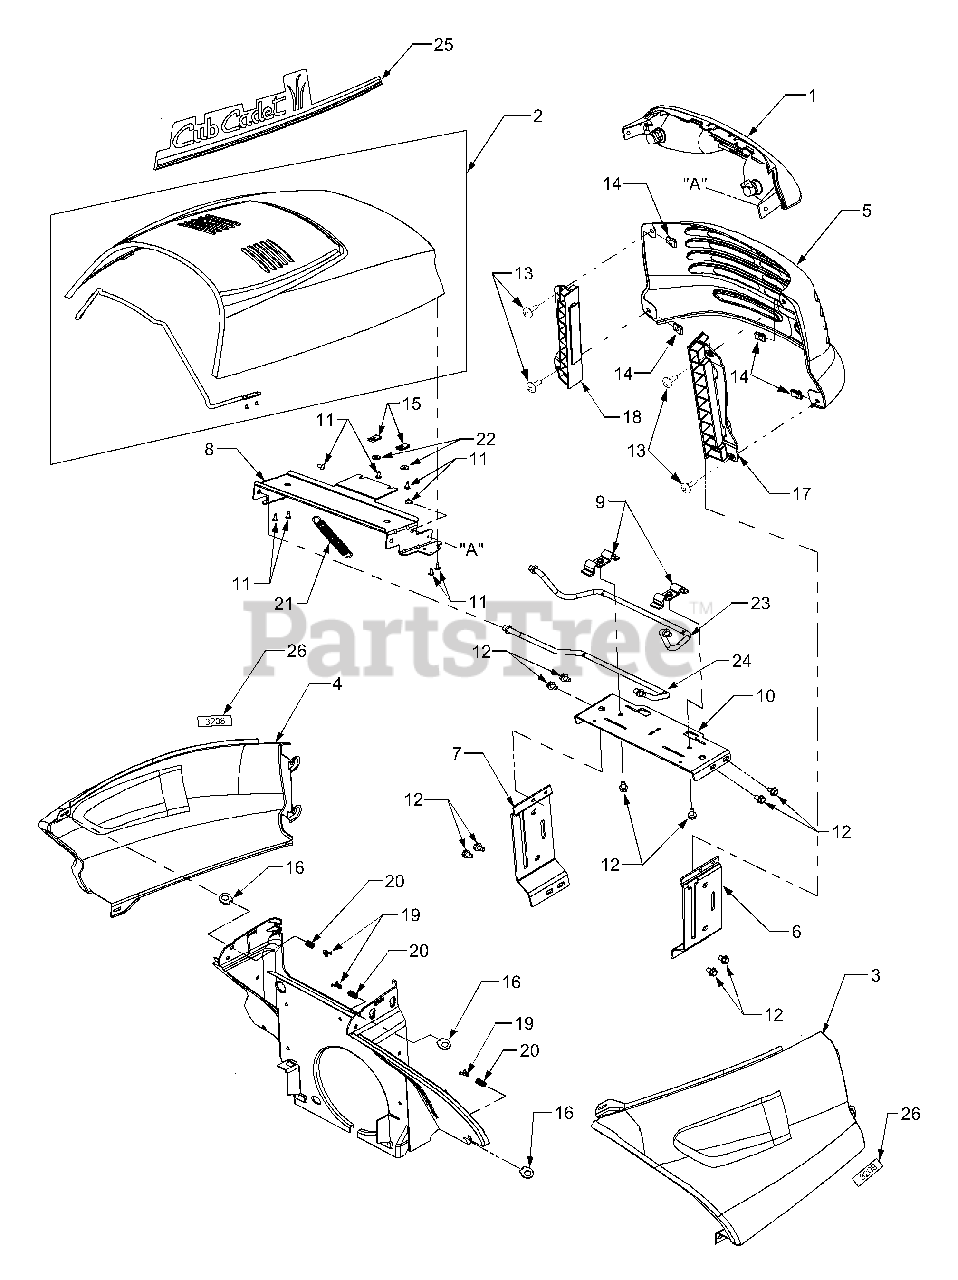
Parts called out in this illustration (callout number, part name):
1	Headlight Assembly
2	Hood w/Support Rod Assembly
3	Side Panel, RH
4	Side Panel, LH
5	Grille, Series 3000
6	Support, Grille - RH
7	Support, Grille - LH
8	Bracket, Upper Hood
9	Bracket, Rod Retainer
10	Support, Hood
11	Screw, Truss Hd, Tapp, #10-16 x .5
12	Screw, Hex Wash. Hd. Tapp 5/16-18 x .5
13	Screw, Phil. Pan Hd. 1/4-20 x .75
14	Nut, U Type Speed, 1/4-20
15	Nut, U-type Speed, #10
16	Latch, 1/4 Turn
17	Mount, Side Panel/Grille RH
18	Mount, Side Panel/Grille LH
19	Clip, Spring
20	Spring, Compression
21	Spring, Extension
22	Washer, Flat, .194 x .62 x .063
23	Rod, Upper Hood
24	Rod, Lower Hood
25	Graphic, Hood - RH
26	Graphic, 3208
